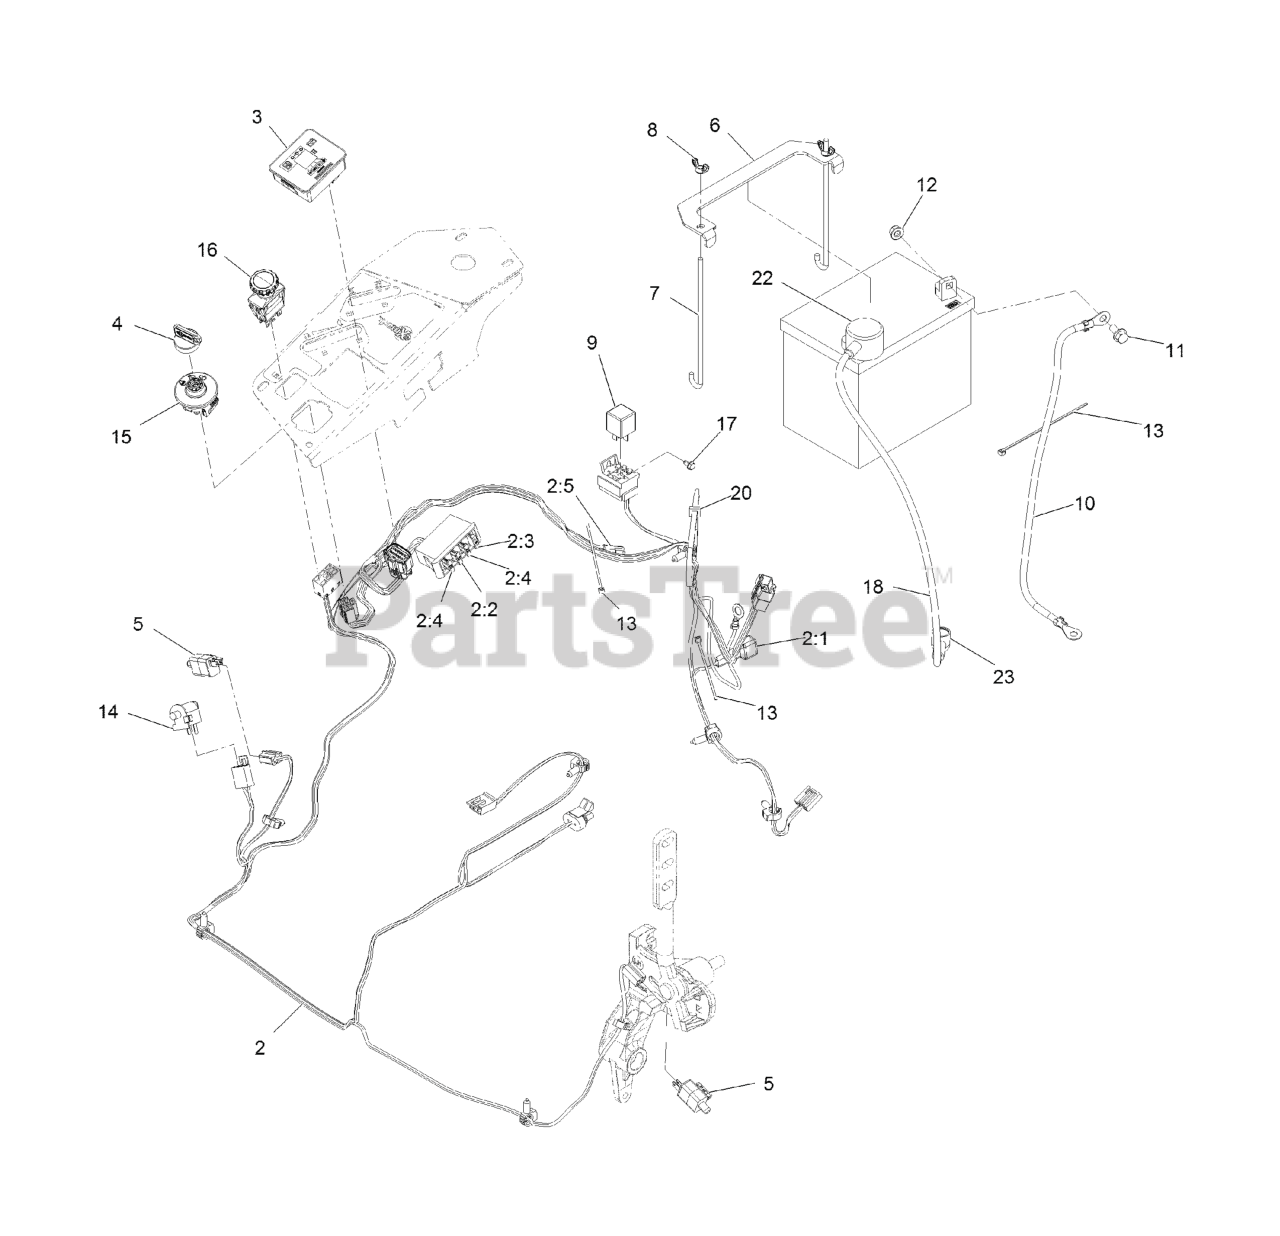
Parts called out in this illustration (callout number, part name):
2	HARNESS-WIRE, MAIN
2:2	FUSE-BLADE, 10 AMP
2:3	FUSE-BLADE, 15 AMP
2:4	FUSE-BLADE, 25 AMP
2:5	CAP-PLUG
3	FUEL/HOUR METER ASM
4	KEYS-IGNITION (SPARE PAIR
4	KEY-IGNITION
6	STRAP-TIE DOWN, BATTERY
7	BOLT-HOLDDOWN
8	WINGNUT
10	CABLE-BATTERY, NEGATIVE
11	SCREW-HHF
12	NUT-HF, NI
13	TIE-CABLE
14	SWITCH-BAIL
15	SWITCH-IGNITION
16	SWITCH-PTO, 10 AMP
17	SCREW-HWH
18	CABLE-BATTERY, POSITIVE
20	TIE-PLASTIC
22	INSULATOR-BATTERY
23	INSULATOR-SOLENOID
